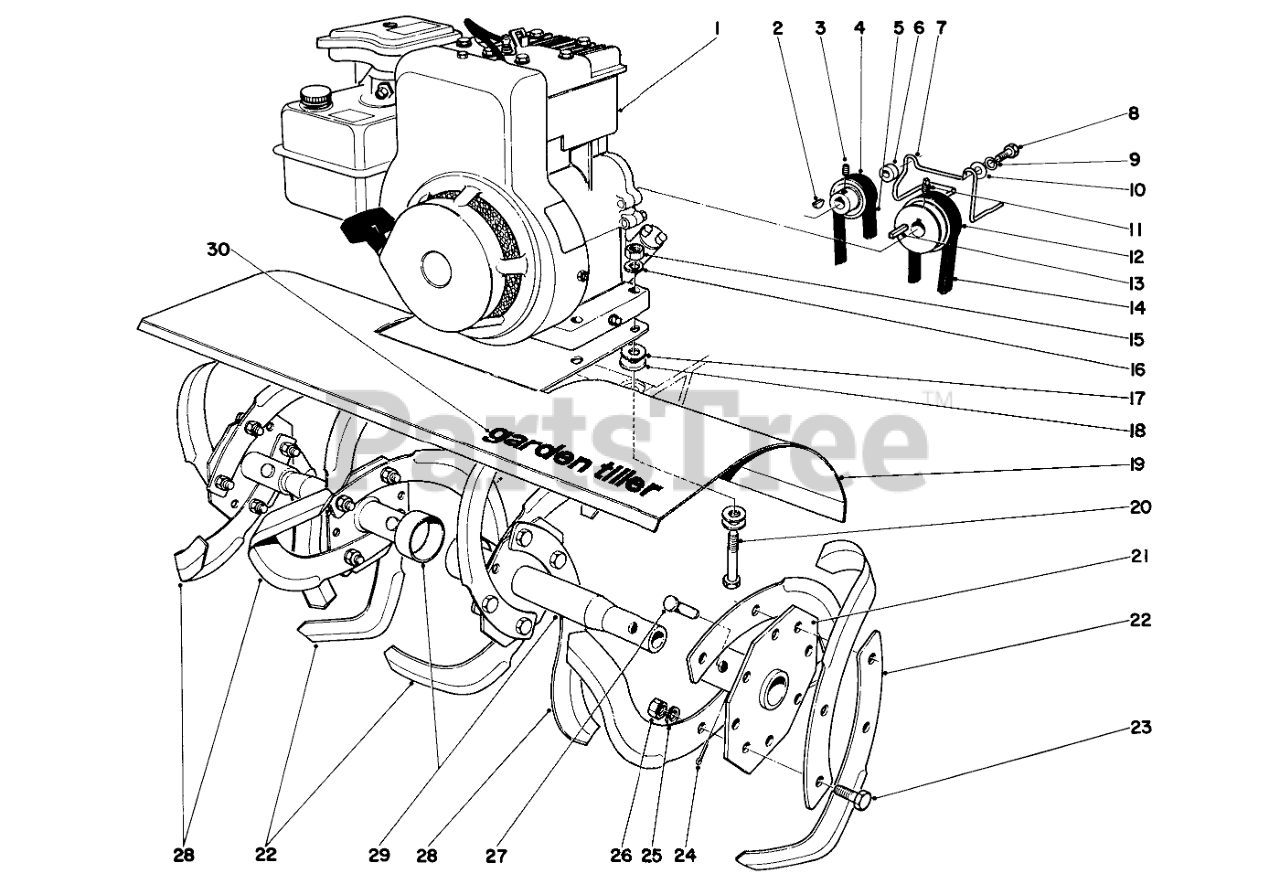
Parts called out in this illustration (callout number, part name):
1	Engine
2	KEY-WOODRUFF
3	SCREW-SET
4	Pulley
5	V-BELT
6	SPACER
7	BELT GUIDE
8	SCREW-HH
9	WASHER-LOCK
10	WASHER-FLAT
11	SCREW-SET, HSH
12	Engine Pulley
13	KEY-SQUARE
14	Belt
15	NUT-HEX
16	WASHER-LOCK
17	WASHER-FLAT
18	WASHER-FLAT
19	Shield
20	SCREW-HH
21	Axle Hub
22	RH TINE
23	SCREW-HH
24	PIN-COTTER
25	WASHER-LOCK
26	NUT-HEX
27	TINE PIN
28	LH TINE
29	Axle Hub
30	Decal
